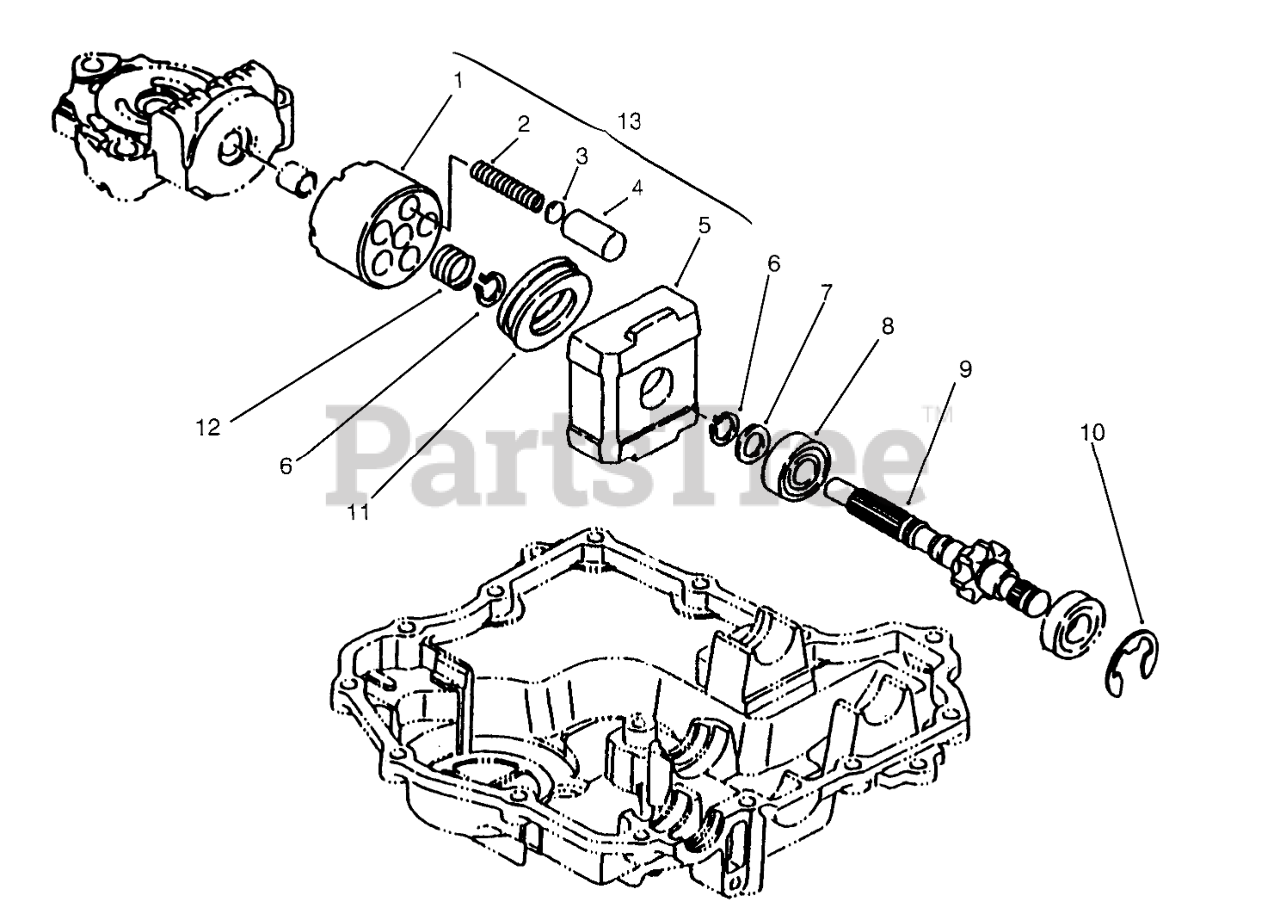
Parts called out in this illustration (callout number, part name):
5	Housing (Only On: 72043,72063,72103)
6	Ring-Snap (Only On: 72043,72063,72103)
7	Washer (Only On: 72043,72063,72103)
8	Bearing-Ball (Only On: 72043,72063,72103)
9	Shaft-Motor (Only On: 72043,72063,72103)
10	E Ring (Only On: 72043,72063,72103)
11	Bearing-Thrust (Only On: 72043,72063,72103)
13	Cylinder ASM INCL 1 -4 (Only On: 72043,72063,72103)
